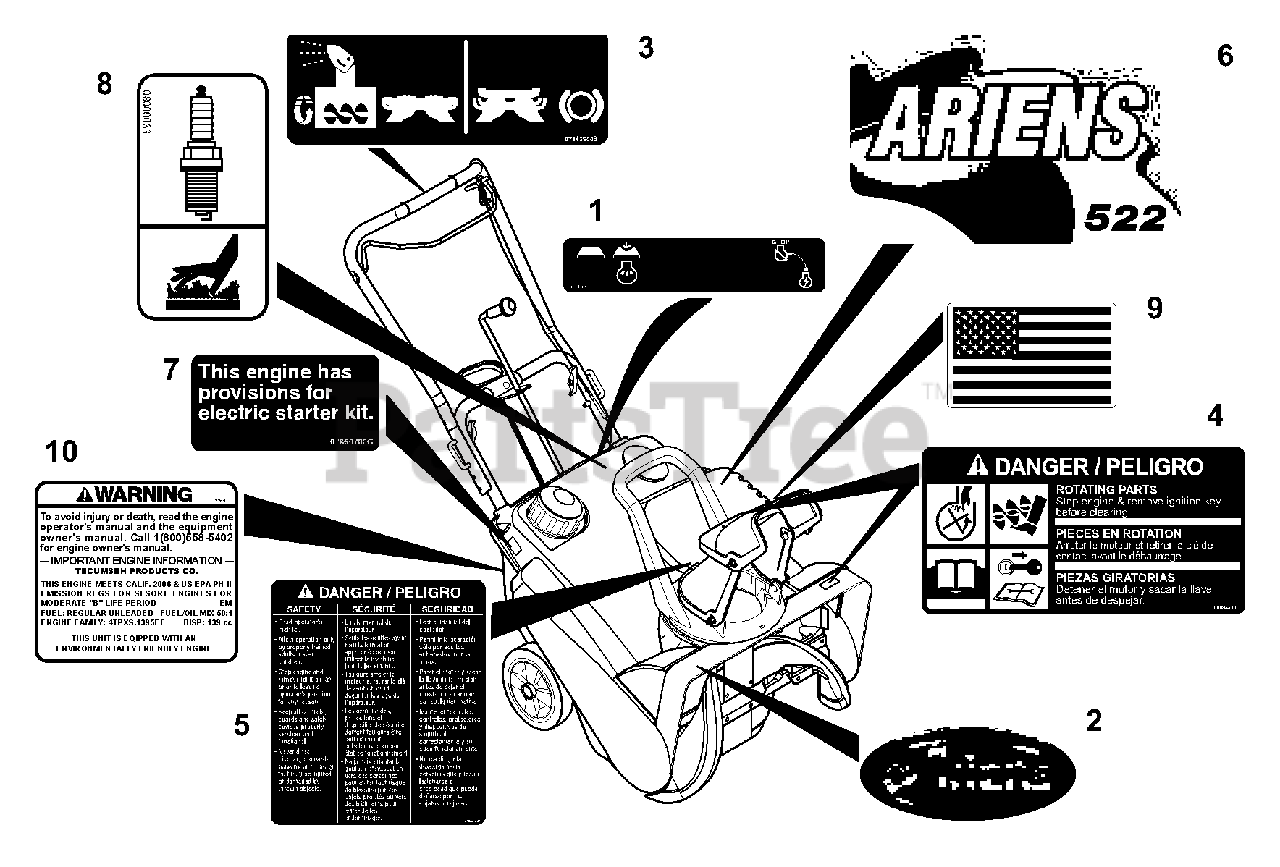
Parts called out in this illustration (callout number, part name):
1	DECAL-PANEL
2	DECAL-ARIENS JEWEL
3	DECAL-AUGER/IMPELLER BAIL
4	DECAL, SAFETY-AUGER & CHUTE,SS
5	DECAL-DANGER CHUTE (SS)
6	DECAL - 522
7	DECAL, ELECTRIC START
8	DECAL, SPARK PLUG ACCESS
9	DECAL, AMERICAN FLAG
10	DECAL, SUPPLEMENTAL CARB
